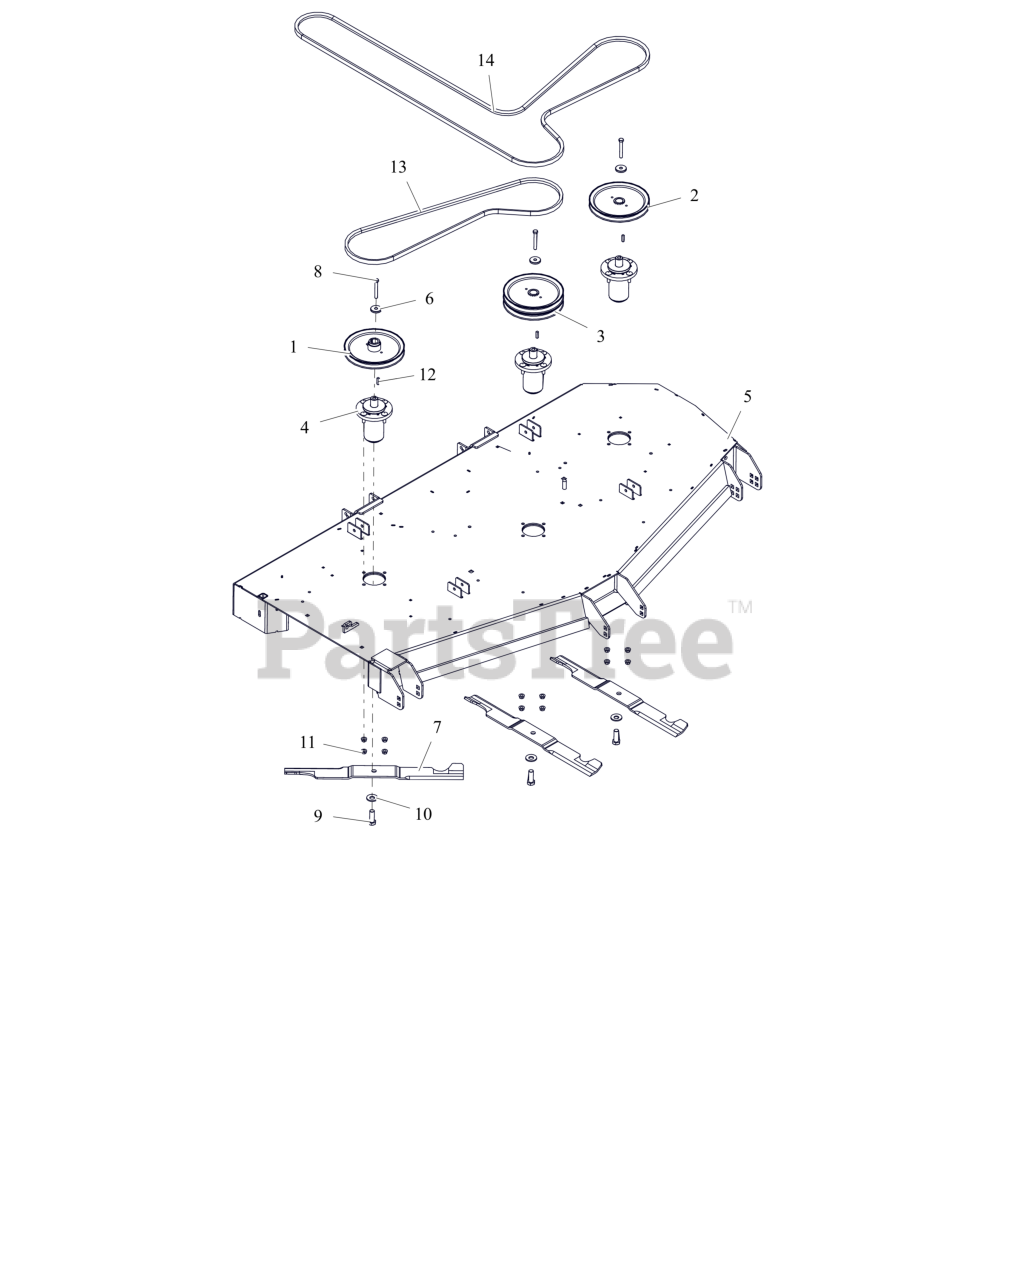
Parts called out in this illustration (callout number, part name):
1	SHEAVE, SINGLE 1.00" ID X 8.25" OD
2	SHEAVE, SINGLE 1.00" X 8.25" OD
3	SHEAVE-DOUBLE 1.00"ID X 8.25"OD
4	ASM, MAINT FREE ALUM SPINDLE
5	WLDMT, 72" SIDE DISCH DECK-X3 (RED) W/ SAFETY DECALS
6	RETAINER, SHEAVE
7	BLADE, 72"
8	BLT, HEX .38-16X2.75 G8 ZCC
9	BLT, HEX .62-18X1.75 G8 ZCC
10	WSHR-BLVL .669X1.535X.138
11	NUT-LK-CTR-FLG .375-16 GF ZCC
12	KEY, SQ .25X.25X1.00 RC 40-50
13	V-BELT, B-COGGED
14	V-BELT, B SECTION
